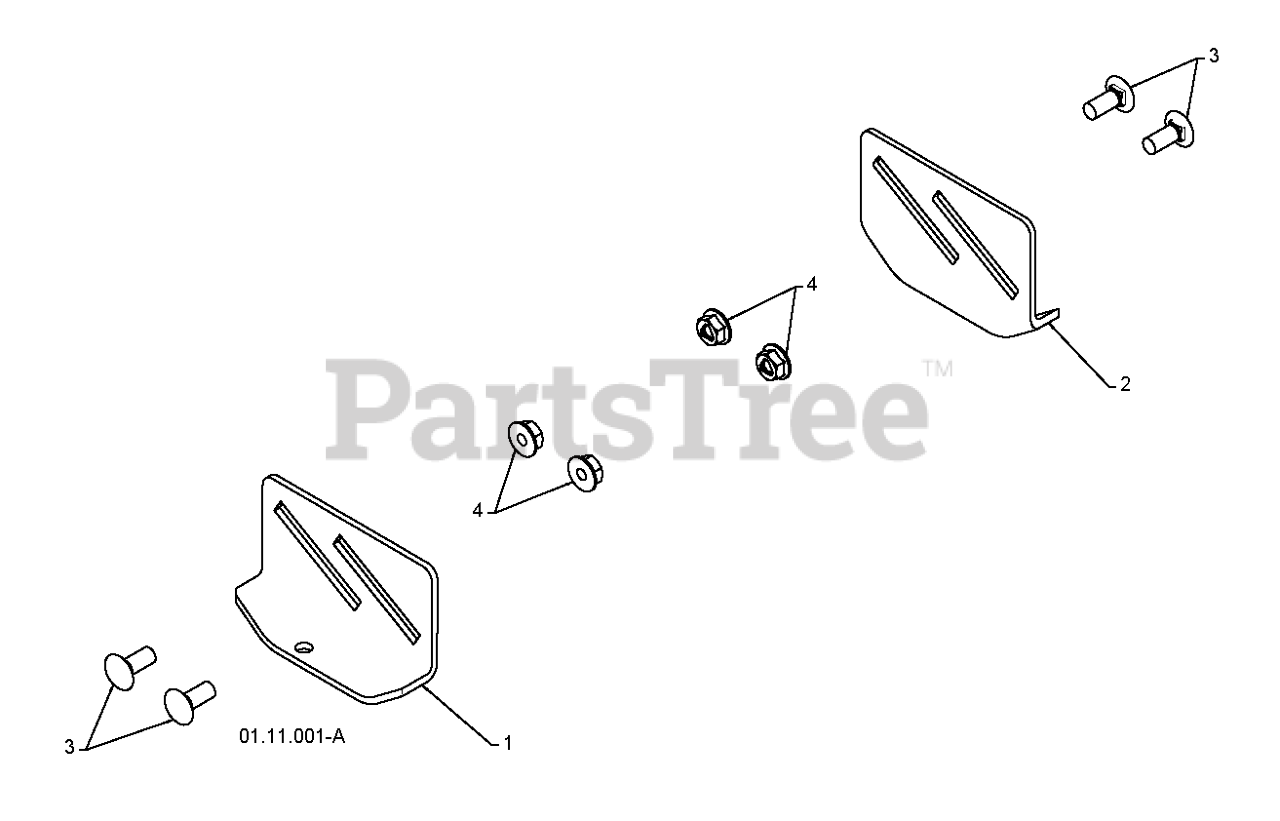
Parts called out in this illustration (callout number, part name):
1	SKID PLATE LH
2	SKID PLATE RH
3	BOLT
4	NUT.LOCK.5/16-18
